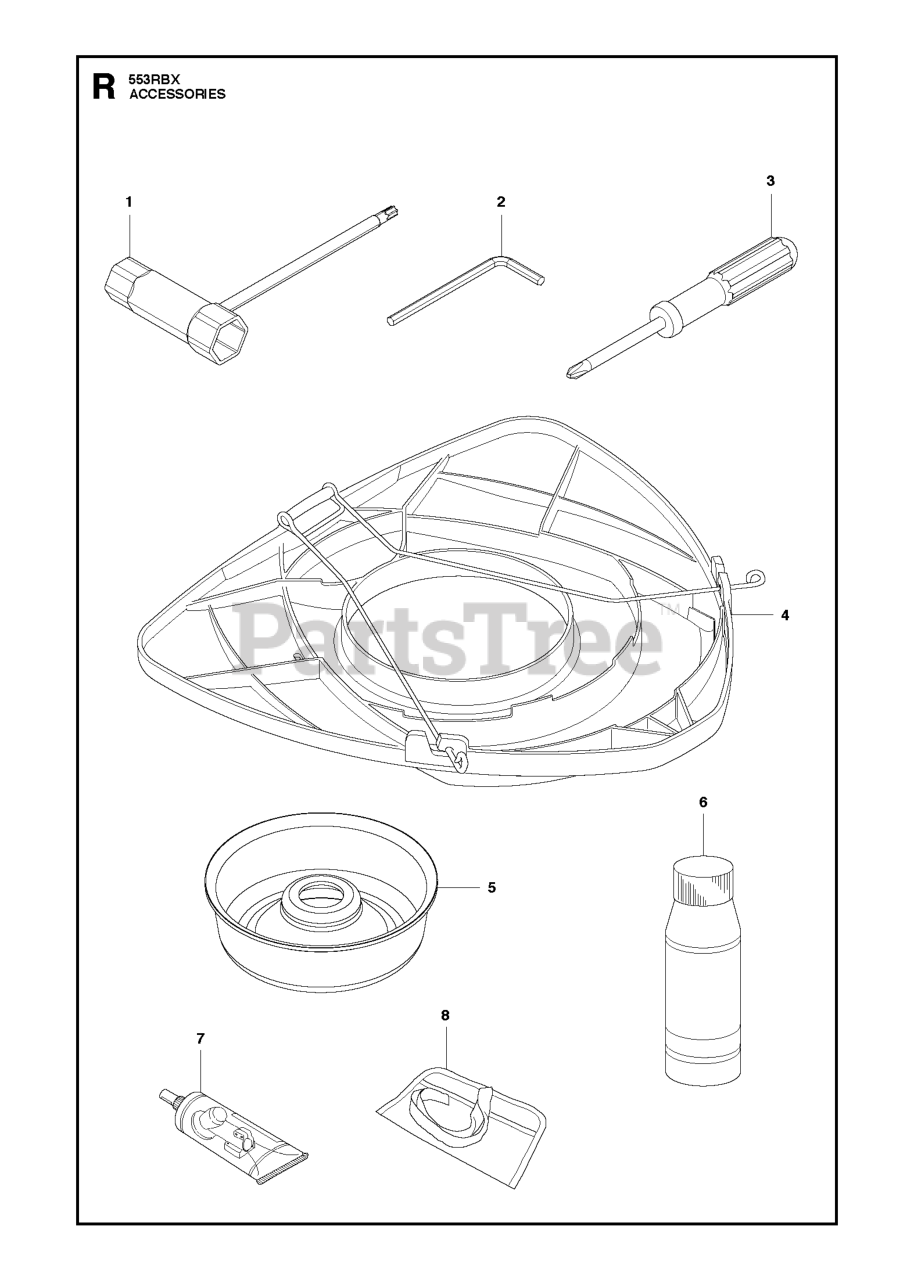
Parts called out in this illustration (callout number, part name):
3	SCREWDRIVER
4	TRANSPORT GUARD
6	Air Filter Oil, HVA 1L Bottle
7	BEVEL GEAR GREASE
